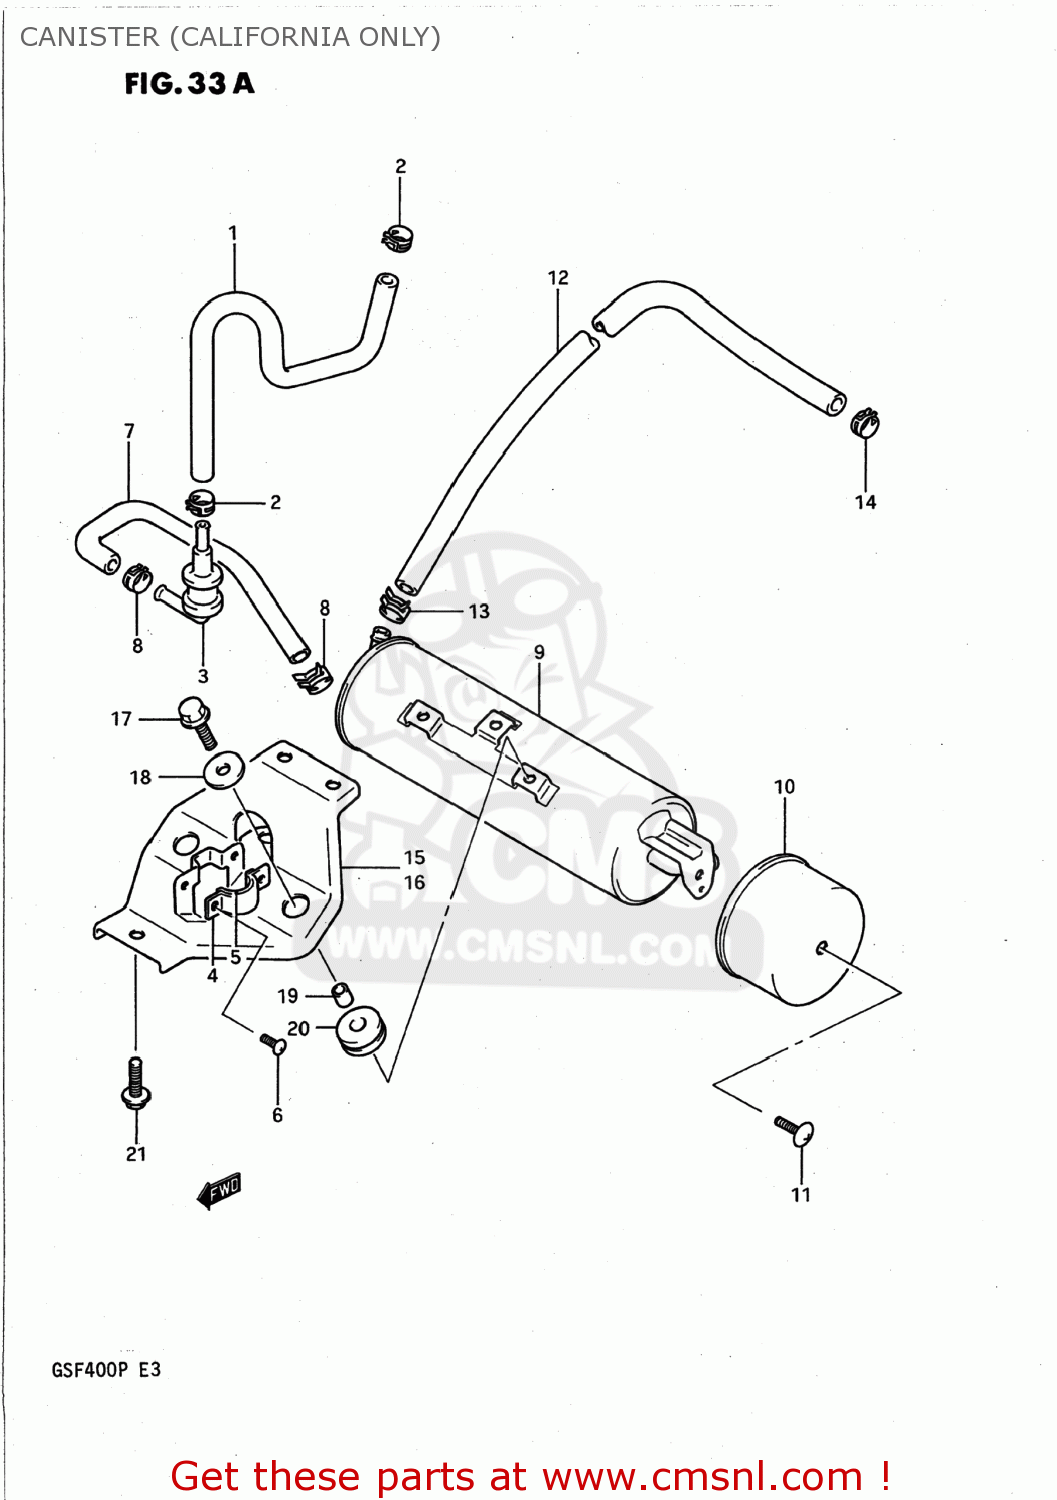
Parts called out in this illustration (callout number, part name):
1	HOSE
2	(CA) CLIP
3	VALVE,FUEL TANK BREATHER
4	PLATE,FUEL TANK BREATHER NO.2
5	CUSHION
6	SCREW
7	HOSE,VALVE & CANISTER
8	(CA) CLIP
9	CANISTER ASSEMBLY,CHARCOAL
10	COVER,CANISTER
11	SCREW
12	HOSE(5.4X11.4X600)
13	CLAMP
14	(CA) CLIP
15	BRACKET,CANISTER
16	CUSHION
17	BOLT
18	WASHER (6.5X24X1.6)
19	SPACER
20	CUSHION
21	BOLT 6X20
